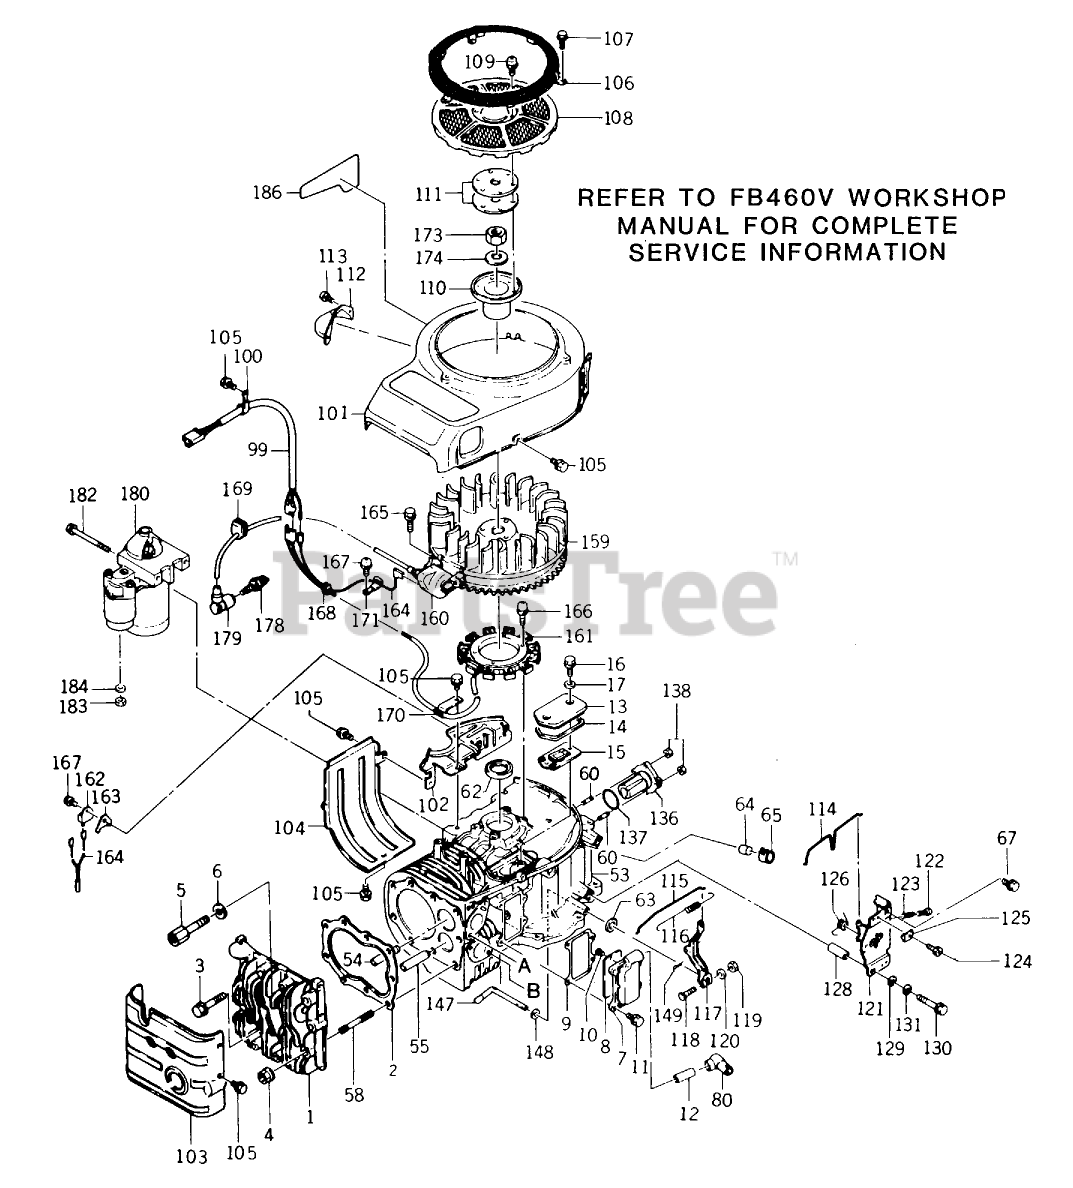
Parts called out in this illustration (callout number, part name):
1	Head-Cylinder
6	Washer
7	Cover-Valve Chamber
11	Flanged Bolt 6x16
15	Breather
53	Crankcase Complete (includes items 54 55).
54	Guide-Intake Valve
55	Guide-Exhaust Valve
62	Oil Seal
63	SEAL-OIL (VC6X10X2.6)
67	BOLT-FLANGED (6X10)
99	Harness
101	Fan Housing
102	Fan Housing
105	BOLT-FLANGED (6X10)
109	Screw 6x16
110	Bracket
111	Shim T-1.20
114	LINK-Choke
117	Arm ASM
118	Bolt (6X28)
119	NUT-HEX (6mm)
120	Washer-Plain (6mm)
121	Control Panel Assy (includes items 122, 123, 124, 125 126)
122	Screw 4 x 25
131	Lockwasher
147	Arm-Pivot
148	Washer
149	Pin-Snap (1.2 X 21.2)
159	Flywheel Complete
161	Charging Coil
162	Igniter
164	Lead Wire
168	Grommet
169	Grommet
178	Spark Plug
180	Electric Starter Assy-see section 9-7 for parts breakdown
183	Nut-Hex, Small (8mm)
184	WASHER 5/16 SAE
